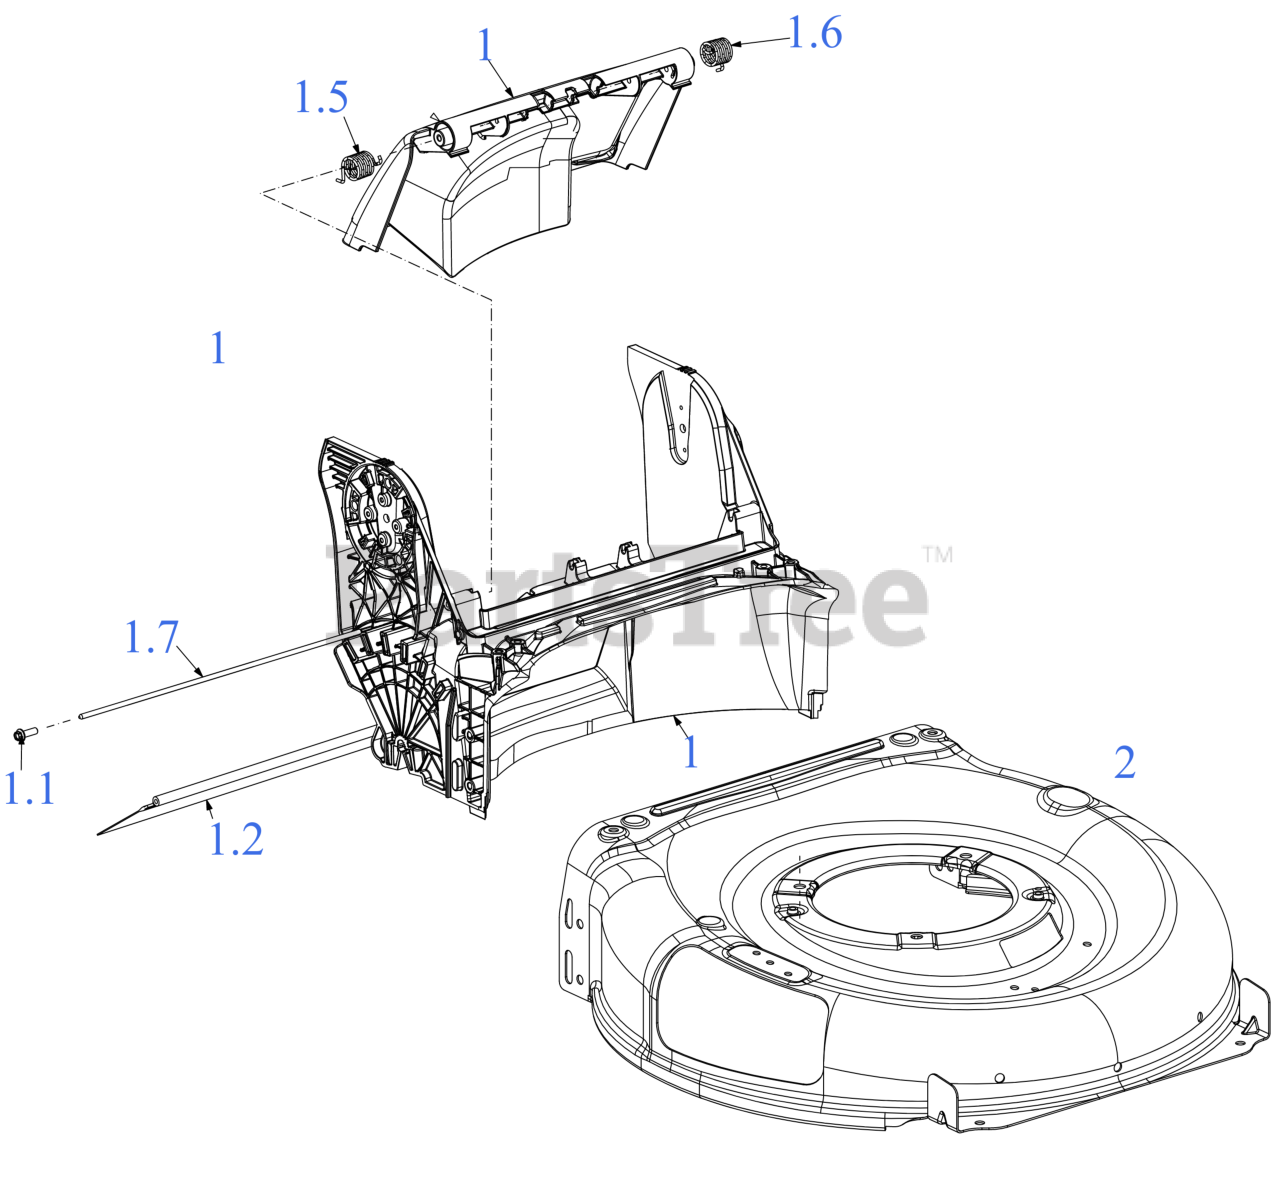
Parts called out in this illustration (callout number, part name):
1	BAFFLE ASSEMBLY (REAR)
1.1	SCREW 1/4 x .750
1.2	TRAILSHIELD
1.5	TORSION SPRING (RH)
1.6	TORSION SPRING (LH)
1.7	REAR DOOR PIVOT ROD
